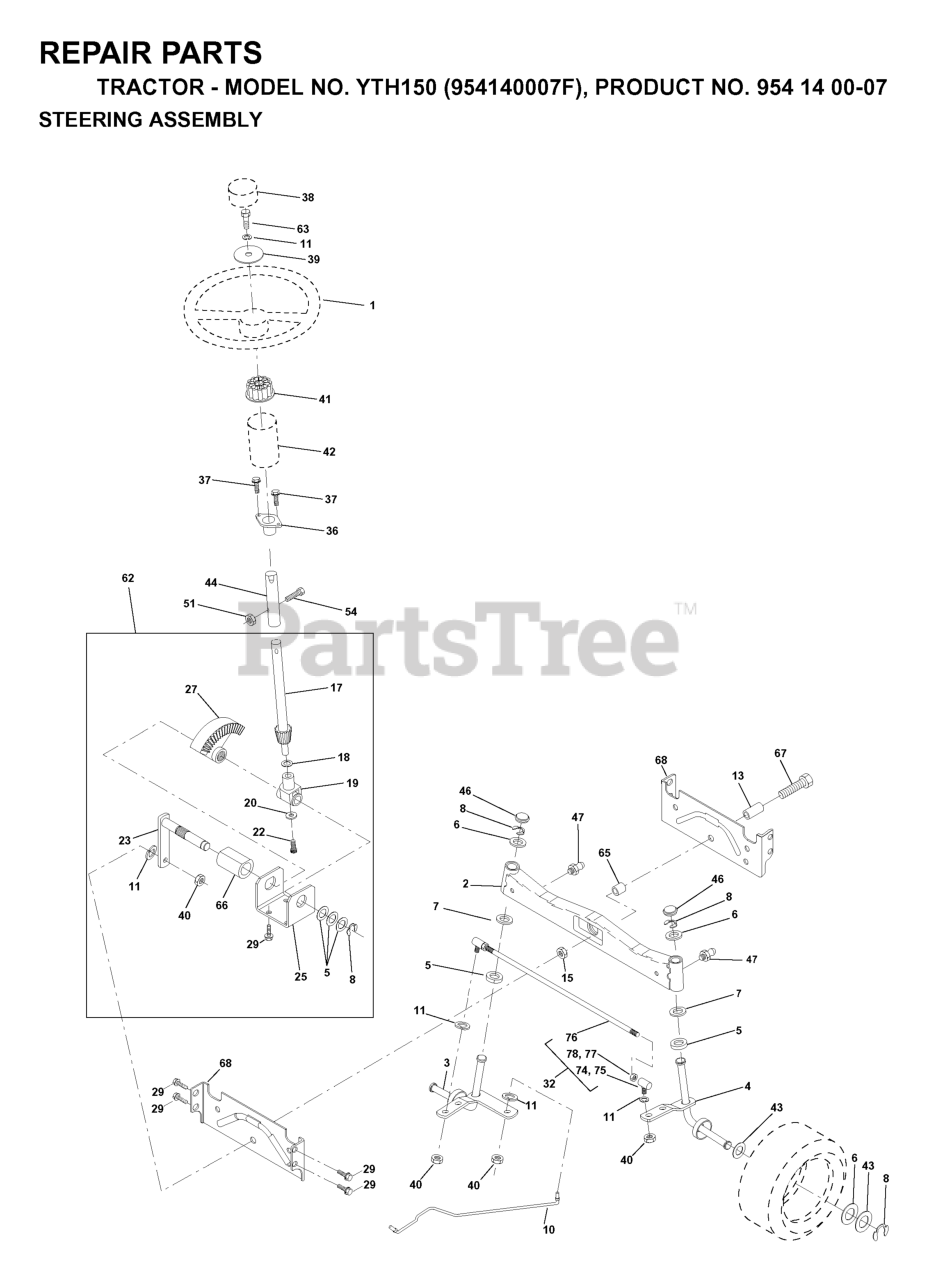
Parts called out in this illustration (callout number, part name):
1	STEERING WHEEL
2	FRONT AXLE ASSY
3	SPINDLE ASM LH
4	SPINDLE ASM RH
5	THRUST WASHER
9	BRNG T
10	LINK.DRAG.DROPPED.LT
11	WASHER, LOCK 3/8
13	BEARING AXLE
15	NUT-LOC,FLANGE LT
17	SHAFT ASM STEERING
18	THRUST WASHER
19	SHAFT,SUPPORT
20	WASHER
22	SCREW HEX SOCKET 1/4-20 X 5/8
23	SHAFT PITMAN
25	BRACKET STEERING
27	GEAR.SECTOR
29	SCREW
32	ROD ASSY/TIE BALL
36	BUSHING, STEERING
37	SCREW.TT.#10-32X.5.3/8.FLANGE
38	INSERT,STR WHEEL
39	WASHER T
40	GRIPCO NUT
41	ADAPTER LT
42	BOOT, STEERING
44	EXT SHAFT STEERING
46	CAP.SPINDLE.BLACK
47	ZERK M
51	NUT.71038.31-18.HEX.NYLOCK
54	BOLT.5/16-18X1-1/4 FULL.THREAD
62	KIT, STEERING ASSEMBLY
65	SPACER AXLE
66	BEARING ARM
67	Bolt, Hex 5/8 -11 x 2 - 3/4 Gr. 5
68	AXLE, BRACE
74	JOINT
76	TIE ROD
